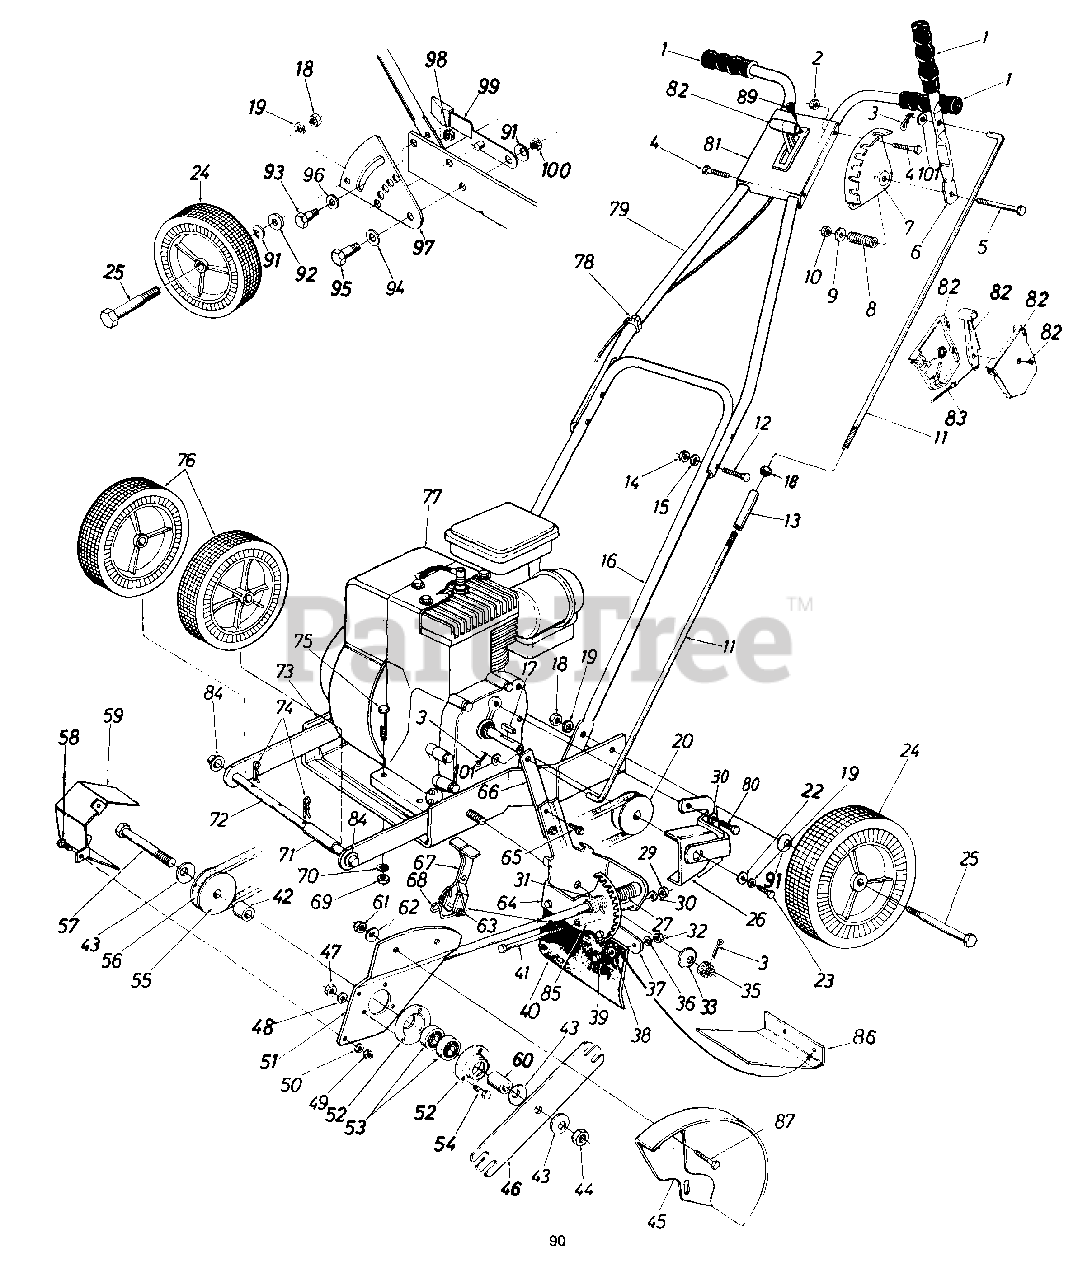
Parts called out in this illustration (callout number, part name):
1	Black Grip
2	Hex L-Nut 1/4-20 Thd.
3	Cotter Pin 1/8" Dia.
4	Hex Bolt 1/4-20 x 1.25" Lg.
5	Hex Bolt 5/16-18 x 2" Lg.
6	Engagement Handle
8	Compression Spring 1.38" Lg.
9	Fl-Wash. .344" I.D.
10	Hex L-Nut 5/16-18 Thd.
11	Clutch Rod Half 18.25" Lg.
12	Carriage Bolt 1/4-20 x 1.25" Lg.
13	Rod Adjustment Link
14	Hex Nut 1/4-20 Thd.
15	L-Wash. 1/4" I.D.
16	Lower Handle
17	Sq. Key 3/16" x .75" Lg.
18	Hex Nut 3/8-16 Thd.
19	L-Wash. 3/8" I.D.
20	Engine Pulley
22	Fl-Wash. .385" I.D.
23	Hex Bolt 3/8-24 x 1" Lg.
24	Rear Wheel Ass'y. 8" x 1.75"
25	Shoulder Bolt .498" Dia.
29	Hex Nut 5/16-18 Thd.
30	L-Wash. 5/16" I.D.
31	Spring Pin Spir. 1/4" Dia.
32	Hex Nut 1/4-20 Thd.
33	Bell-Wash. .535" I.D.
35	Hex Slotted Nut 1/2-20 Thd.
36	L-Wash. 1/4" I.D.
37	Flap Bracket
38	Fl-Wash. .25" I.D.
39	Hex Bolt 1/4-20 x .62" Lg.
41	Hex Bolt 5/16-18 x 4.5" Lg.
42	Spacer 1.030" Lg.
43	Bell-Washer. .63" I.D.
44	Hex Jam L-Nut 5/8-18 Thd.
47	Hex Nut 1/4-20 Thd.
48	L-Wash. 1/4" I.D.
49	Hex Nut 1/4-20 Thd.
50	L-Wash. 1/4" I.D.
53	Ball Bearing .62" I.D.
54	Hex Bolt 1/4-20 x .62" Lg.
55	3/8" "V"-Pulley
56	V-Belt
57	Hex Bolt 5/8-18 x 4.5" Lg.
58	Hex Bolt 1/4-20 x .625" Lg.
59	Belt Guard
60	Sleeve .90" Lg.
61	Hex Nut 5/16-18 Thd.
62	Bell-Wash. .345" I.D.
63	Spring Pin Spir. 1/4" Dia.
66	Arm Extension
67	Adjustment Lever Ass'y.
68	Torsion Spring
69	Hex Nut 5/16-18 Thd.
70	L-Wash. 5/16" I.D.
71	Spacer 1.62" Lg.
72	Axle 8.75" Lg. (Front)
73	Base Ass'y.
74	Hairpin Cotter 1/2" Dia.
75	Hex Bolt 5/16-18 x 1.5" Lg.
76	Front Wheel Ass'y. 7" x 1.50"
77	Engine
78	Cable Tie
79	Upper Handle
80	Hex Bolt 5/16-24 x .5" Lg.
83	Throttle Control Wire 30" Lg.
84	Push Cap 1/2" Dia.
85	Spacer 3.765" Lg.
89	Self-Tap Scr. #10 x .50" Lg.
91	Bell-Wash. .40" I.D.
92	Fl-Wash. .39" I.D.
93	Shld. Bolt .5" Dia.
94	Bell-Wash. .515" I.D.
95	Shld. Bolt .50" Dia.
96	Fl-Wash. .51" I.D. x .94"
99	Spring Adj. Lever
100	Hex Jam Nut 3/8-16 Thd.
101	Fl-Wash. 3/8" I.D.
